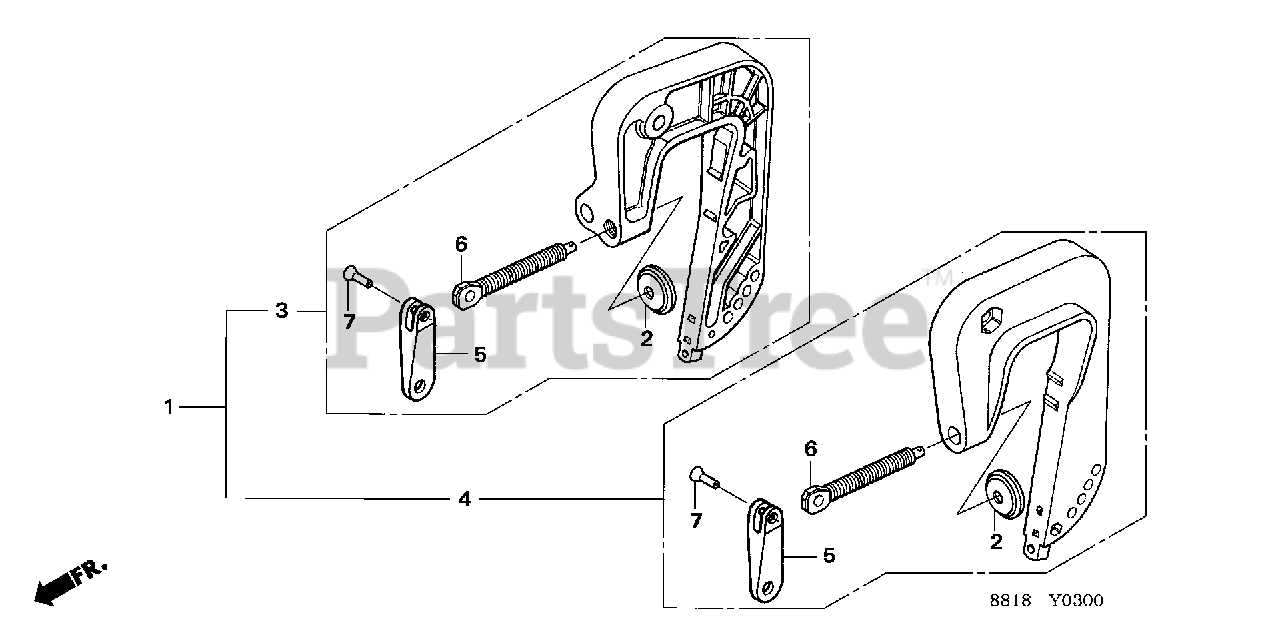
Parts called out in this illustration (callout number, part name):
1	BRACKET KIT, STERN *NH282MU* (OYSTER SILVER METALLIC-U)
2	PLATE, PUSH
3	BRACKET, R. STERN *NH282MU* (OYSTER SILVER METALLIC-U)
4	BRACKET, L. STERN *NH282MU* (OYSTER SILVER METALLIC-U)
5	GRIP, CLAMP
6	SCREW, CLAMP
7	RIVET (4X22.6)
